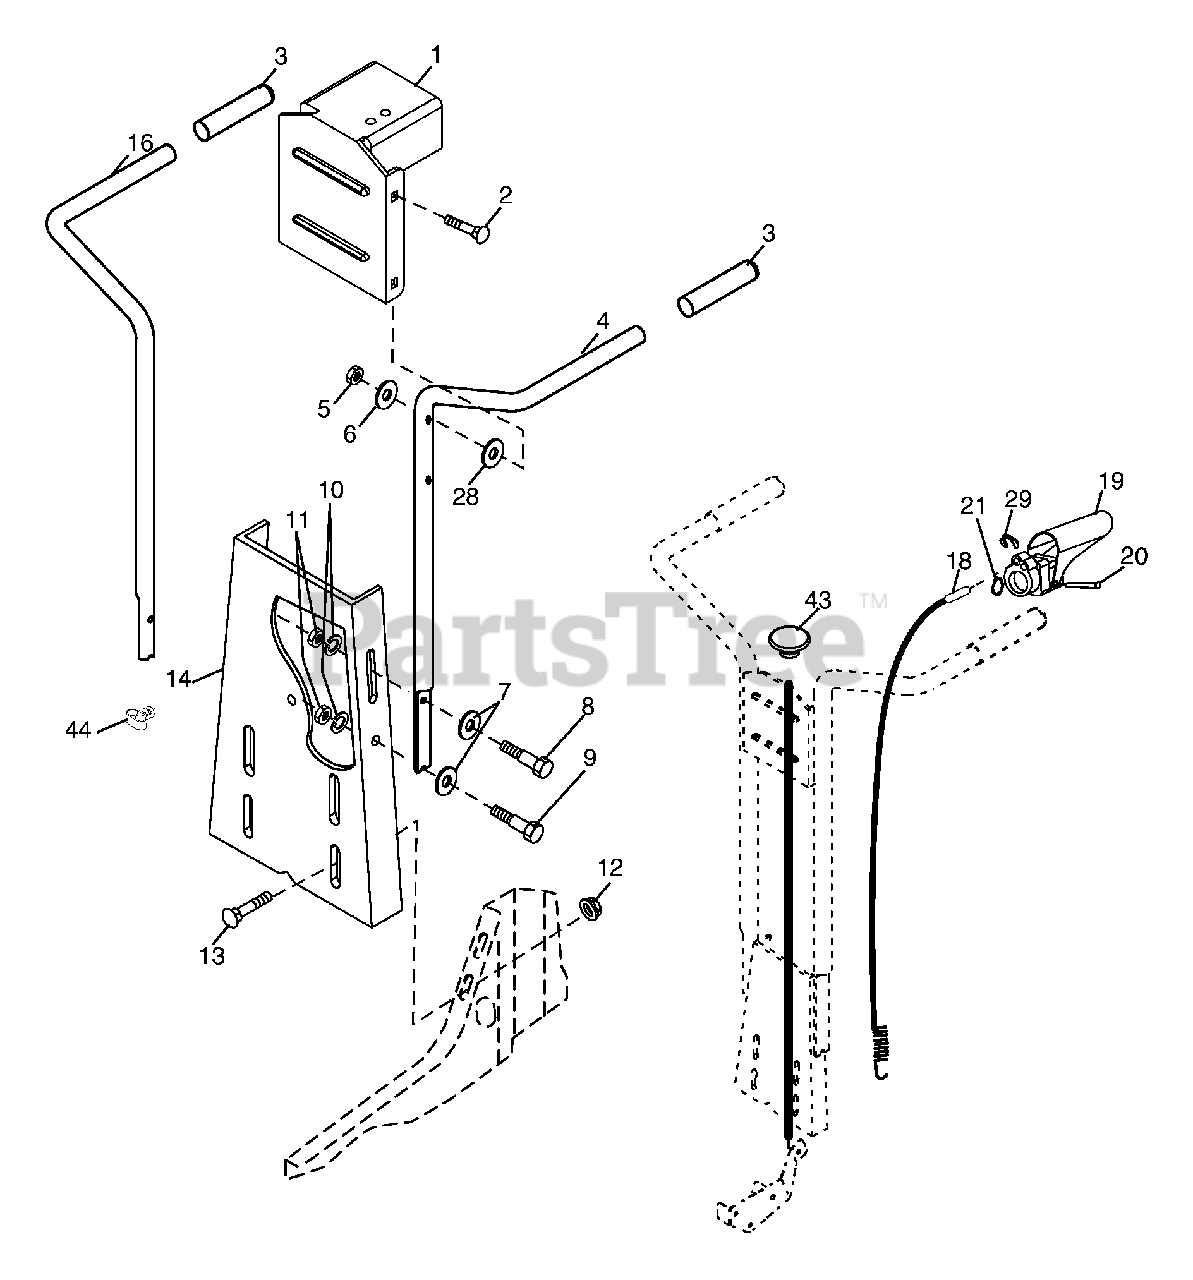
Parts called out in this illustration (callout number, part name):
1	Bracket Handle
2	Bolt, Carriage 5/16-18 unc x 1-1/2
3	Grip, Handle
4	Handle, L.H.
5	Locknut, Crown 5/16-18
6	Washer 11/32 x 11/16 x 16 Ga.
7	Washer 3/8 x 7/8 x 14 Ga.
8	Bolt, Hex Hd. 5/16-18 x 1
9	Bolt, Hex Hd 5/16-18 x 3/4
10	Washer, Lock 5/16
11	Nut, Hex 5/16-18
12	Nut, Flanged 5/16-18
13	Bolt, Carriage 5/16-18 x 3/4 Gr. 5
14	Panel, Handle
16	Handle, R.H.
18	Cable, Control, Tine
19	Lever, Control, Tine
20	Pin, Pivot
21	Ring, Klip
28	Washer 13/32 x 13/16 x 12 Ga.
29	Retaining, Ring
43	Cable Assembly, Reverse
44	Clip
